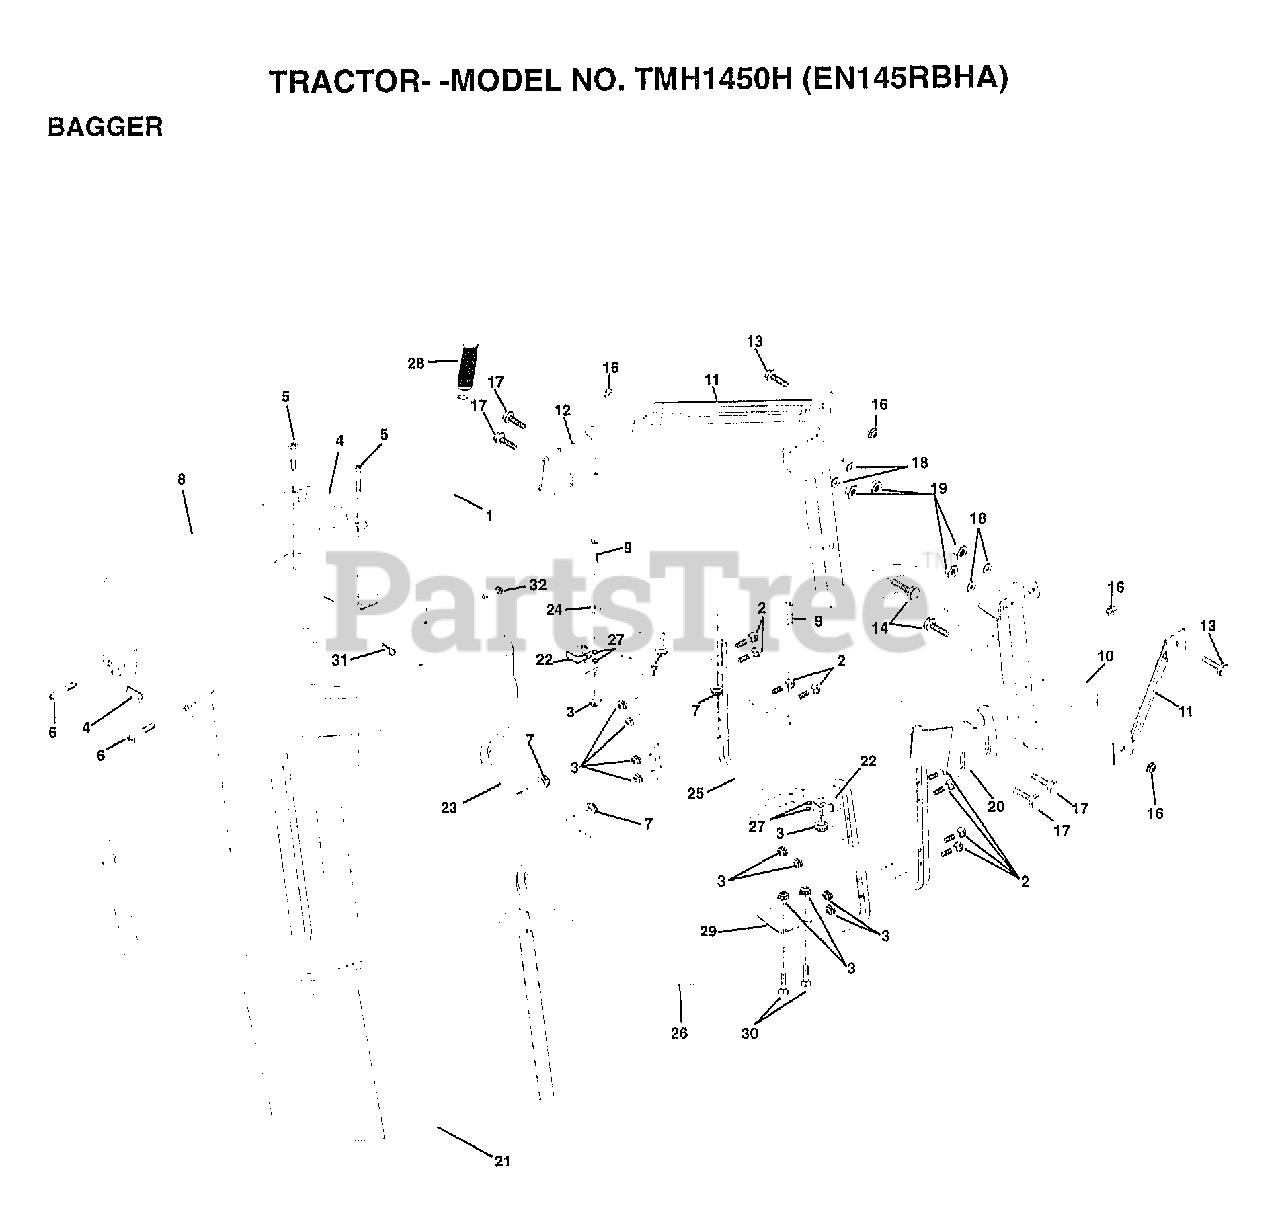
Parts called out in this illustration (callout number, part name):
1	TUBE.HDLE.BAG.CRD
2	BOLT.CARRIAGE.1/4-20X2.0
4	HANDLE.GRAB.BLACK.
5	"SCREW,PAN.HEAD"
7	NUT.WIZ.LOCK
9	BOLT CARRIAGE
10	SUPT.ASM.WLDMNT.BAG.CRD
11	BRKT.SUPT.UPPER.BAG.CRD
12	BRKT.PIVOT.BAG.LH.CRD
13	BOLT
14	BOLT.HEX.3/8-16X2-1/2
17	BOLT
18	WASHER
19	NUT
20	"BRKT.PIVOT.BAG,RH.CRD"
21	BAG.ASM.CRD
22	BRKT.SIDE.BAG.CRD
23	TUBE.UPPER.BAG.CRD
24	TUBE.PIVOT.BAG.CRD
25	TUBE.FT.BAG.CRD
26	TUBE.LOWER.BAG.CRD.
27	GROMMET.EXTRUDED
28	GRIP.HANDLE.BLACK
29	PLATE.STOP.BAG.HDLE.CRD
30	BOLT.CARRIAGE
31	RETAINER M
32	RIVET.DRILL.1.75
